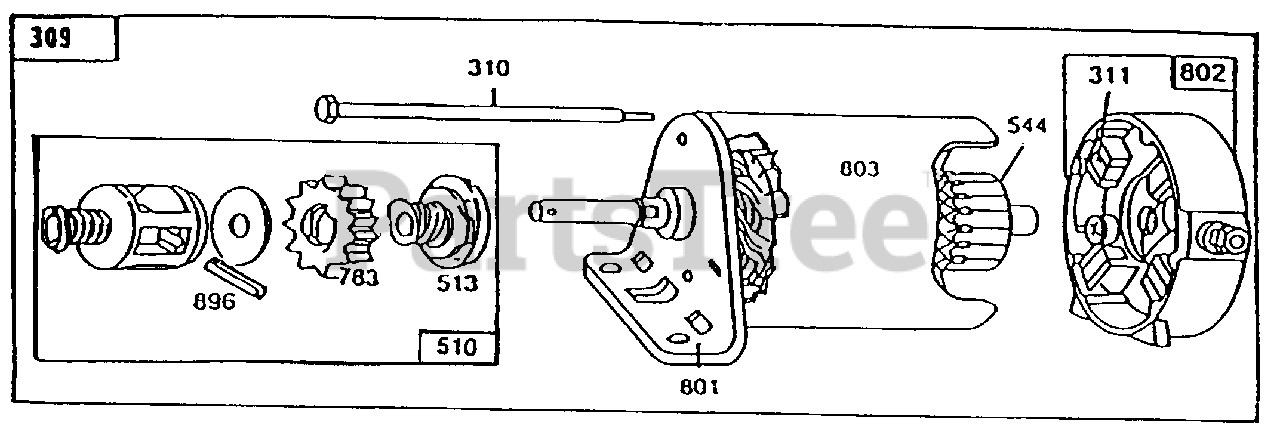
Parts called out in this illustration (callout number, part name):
309	Motor and Drive Ass'y
310	Thru Bolt Ass'y
311	Brush Ass'y
510	Drive Ass'y
544	Armature Ass'y
801	Drive End Cap Ass'y
802	End Cap Ass'y
803	Housing Ass'y
